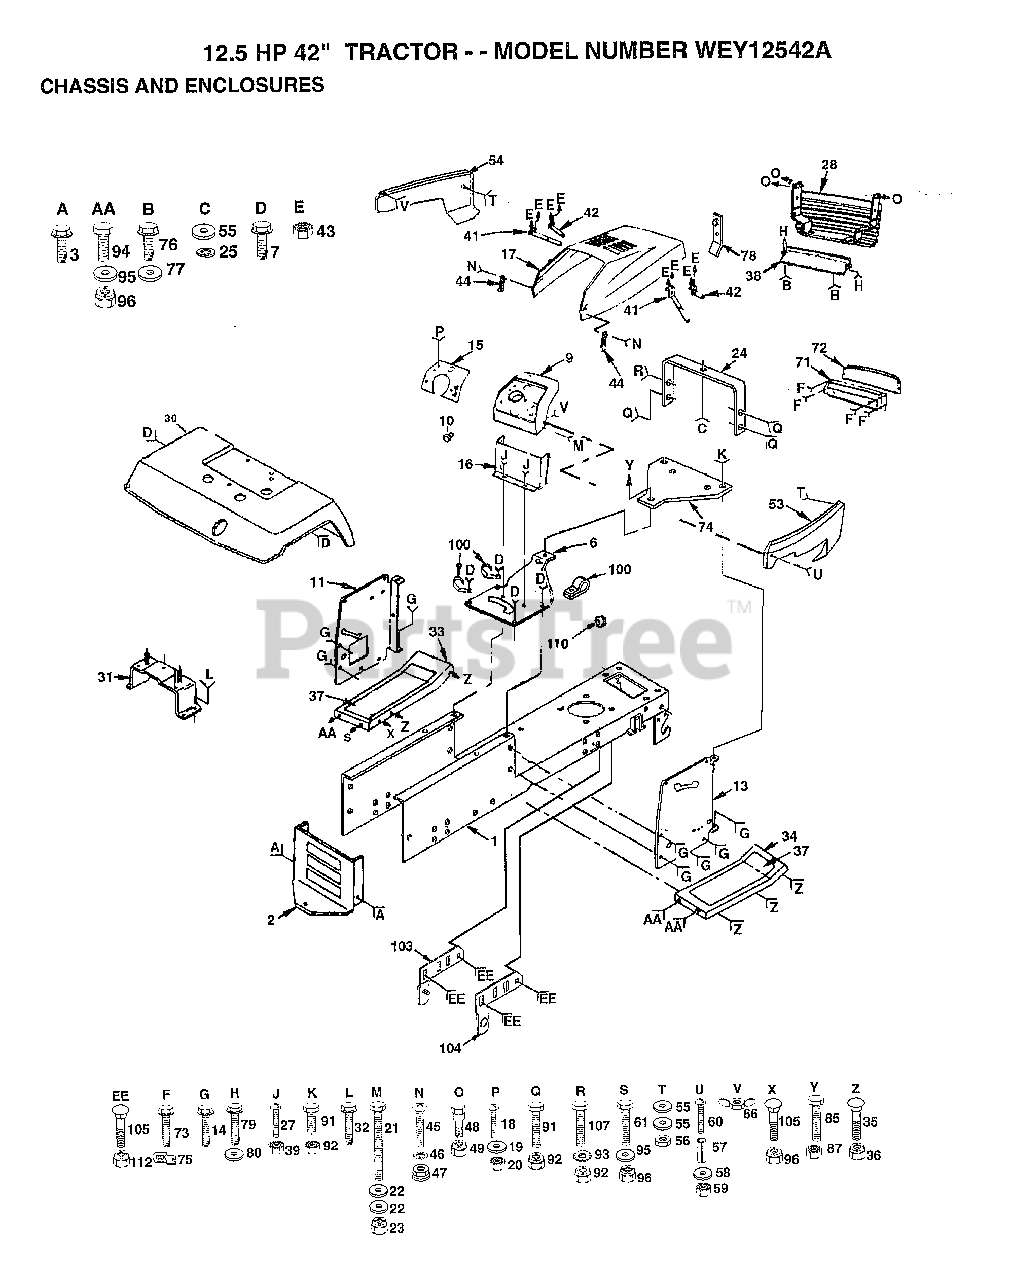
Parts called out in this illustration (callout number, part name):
3	SCREW
6	SADDLE. 6SP
7	SCREW LT
10	PLUG BUTTON T
11	DASH PANEL LH
14	SCREW
18	SCREW
19	WASHER
22	WASHER
24	SUPPORT ASS'Y
25	LOCKWASHER
27	SCREW
31	BRKT FENDER
32	SCREW
35	BOLT
37	"PAD,FOOTREST"
38	"STRAP,GRILL "
43	NUT
44	HOOD LATCH T
45	SCREW
46	LOCKWASHER
47	WELDNUT
54	"PANEL,SIDE LH"
55	WASHER PM
57	SPACER LT
58	WASHER
60	SCREW
72	LENS LT
75	"""J"" FASTENER LT"
76	SCREW
77	WASHER
79	SCREW HEX CRT
80	WASHER
85	BOLT
93	LOCKWASHER
95	WASHER
100	CLIP T
103	PIVOT BRKT LH
104	PIVOT BRKT RH
107	BOLT
112	NUT
